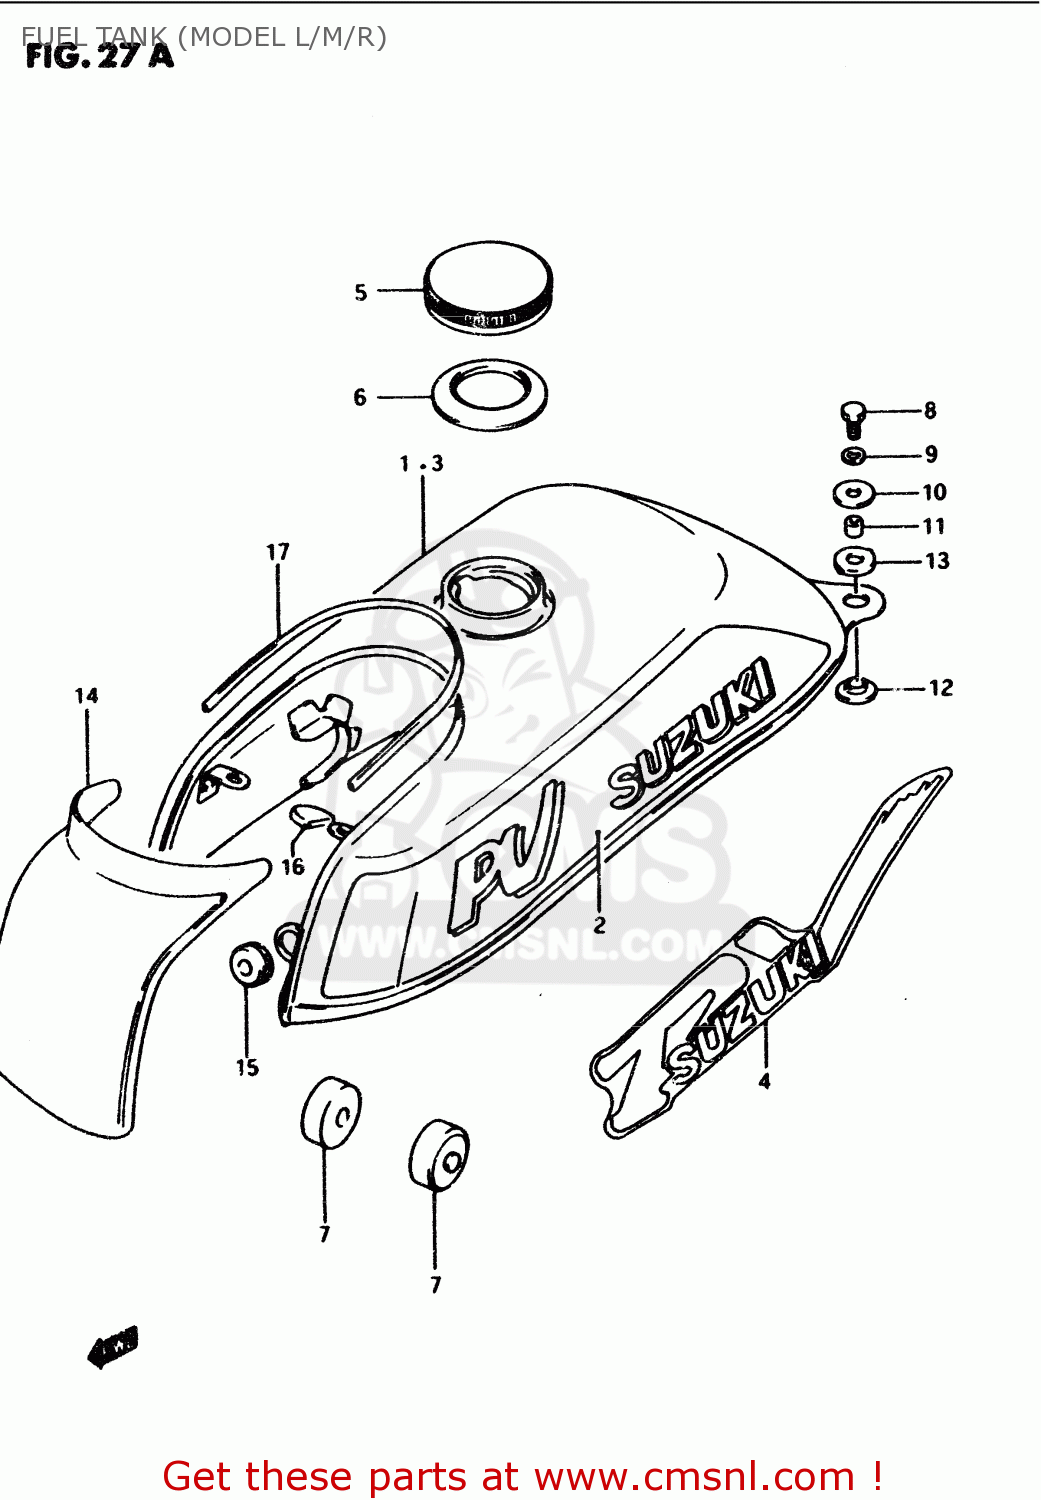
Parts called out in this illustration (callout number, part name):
1	TANK ASSY, FUEL (BLACK)
2	EMBLEM, FUEL TANK,RH
3	TANK ASSY, FUEL (BLACK)
4	EMBLEM
5	CAP,FUEL TANK
6	GASKET (NAS)
7	CUSHION
8	BOLT
9	WASHER,LOCK
10	WASHER (6.5X24X1.6)
11	SPACER (6.8X10X10)
12	CUSHION
13	CUSHION
14	COVER,FUEL TANK FR
15	CUSHION
16	CUSHION
17	MOLDING
